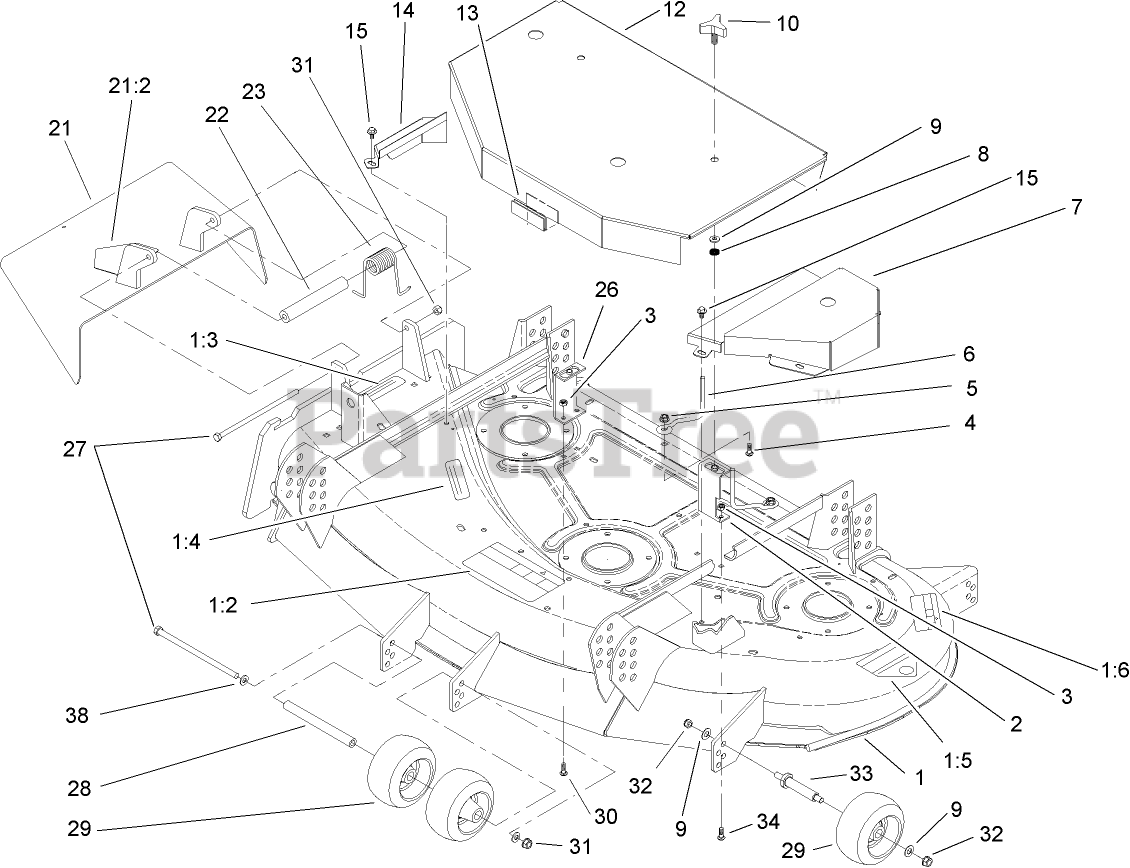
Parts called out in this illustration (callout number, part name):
1	44in DECK W/ DECALS
1:2	DECAL-DANGER, THROWN OBJECT
1:3	DECAL-DANGER
1:4	DECAL-DANGER
1:5	DECAL-DANGER
1:6	DECAL-TORQUE
2	LH COVER BRACKET ASM
3	NUT-LOCK, NI
4	BOLT-CARR
5	NUT-HF
6	ROD-BELT
7	COVER-DECK, LH
8	RING-RETAINING
9	WASHER-FLAT
12	COVER-CENTER
13	TRIM-JIFFY
14	COVER-DECK, RH
15	SCREW-HWH
21	Deflector ASM
21:2	DECAL-DANGER
22	SPACER
23	SPRING-TORSION
26	RH COVER BRACKET ASM
27	SCREW-HH
28	SPACER-WHEEL
29	WHEEL-GAGE
30	BOLT-CARR
31	NUT-LOCK, NI
32	NUT-LOCK, NI
33	SPACER
34	SCREW-CARR
38	WASHER-PLAIN
